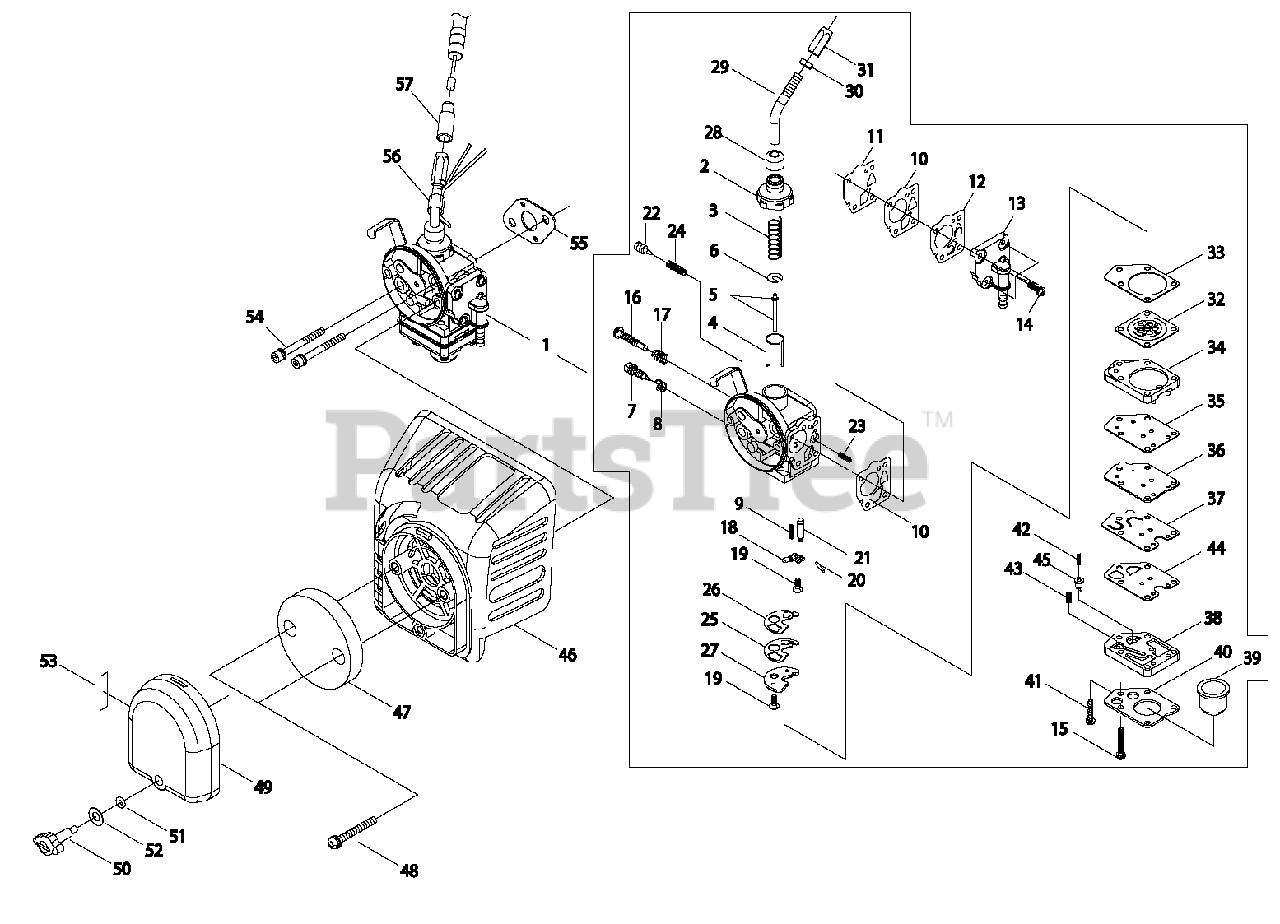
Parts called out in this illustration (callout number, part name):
1	CARBURETOR
2	CAP, CARBURETOR
3	SPRING, THROTTLE
4	VALVE, SLIDE
5	NEEDLE, JET
6	WASHER, SPRING SUPPORT
7	SCREW, MAIN ADJUST
8	SPRING
9	SPRING
10	GASKET, DIAPHRAGM
11	DIAPHRAGM, METERING
12	VALVE, PUMP
13	PUMP BODY
14	SCREW
15	SCREW 3×20
16	SCREW, IDLE ADJUST
17	SPRING
18	LEVER, METERING
19	SCREW M3×8
20	PIN, METERING LEVER
21	VALVE, INLET NEEDLE
22	SCREW, SLOW AIR
23	SPRING
24	SPRING
25	VALVE, CHECK
26	PACKING
27	PLATE
28	CAP, DUST
29	PIPE, CABLE ADJUSTER
30	NUT, LOCK
31	ADJUSTER, CABLE
32	DIAPHRAGM, METERING
33	GASKET, METERING DIAPHRAGM
34	COVER, PUMP
35	GASKET
36	PLATE, PUMP
37	VALVE, CHECK
38	BODY, PURGE
39	BULB, PURGE
40	RETAINER, PURGE BULB
41	SCREW
42	SPRING
43	SPRING
44	GASKET
45	VALVE, CHECK
46	CASE, AIR FILTER
47	FILTER, AIR
48	SCREW
49	COVER, AIR FILTER
50	THUMBSCREW
51	O-RING
52	WASHER, CONE M6
53	LABEL, CHOKE
54	BOLT
55	GASKET, CARBURETOR
56	SLEEVE
57	CAP, DUST
